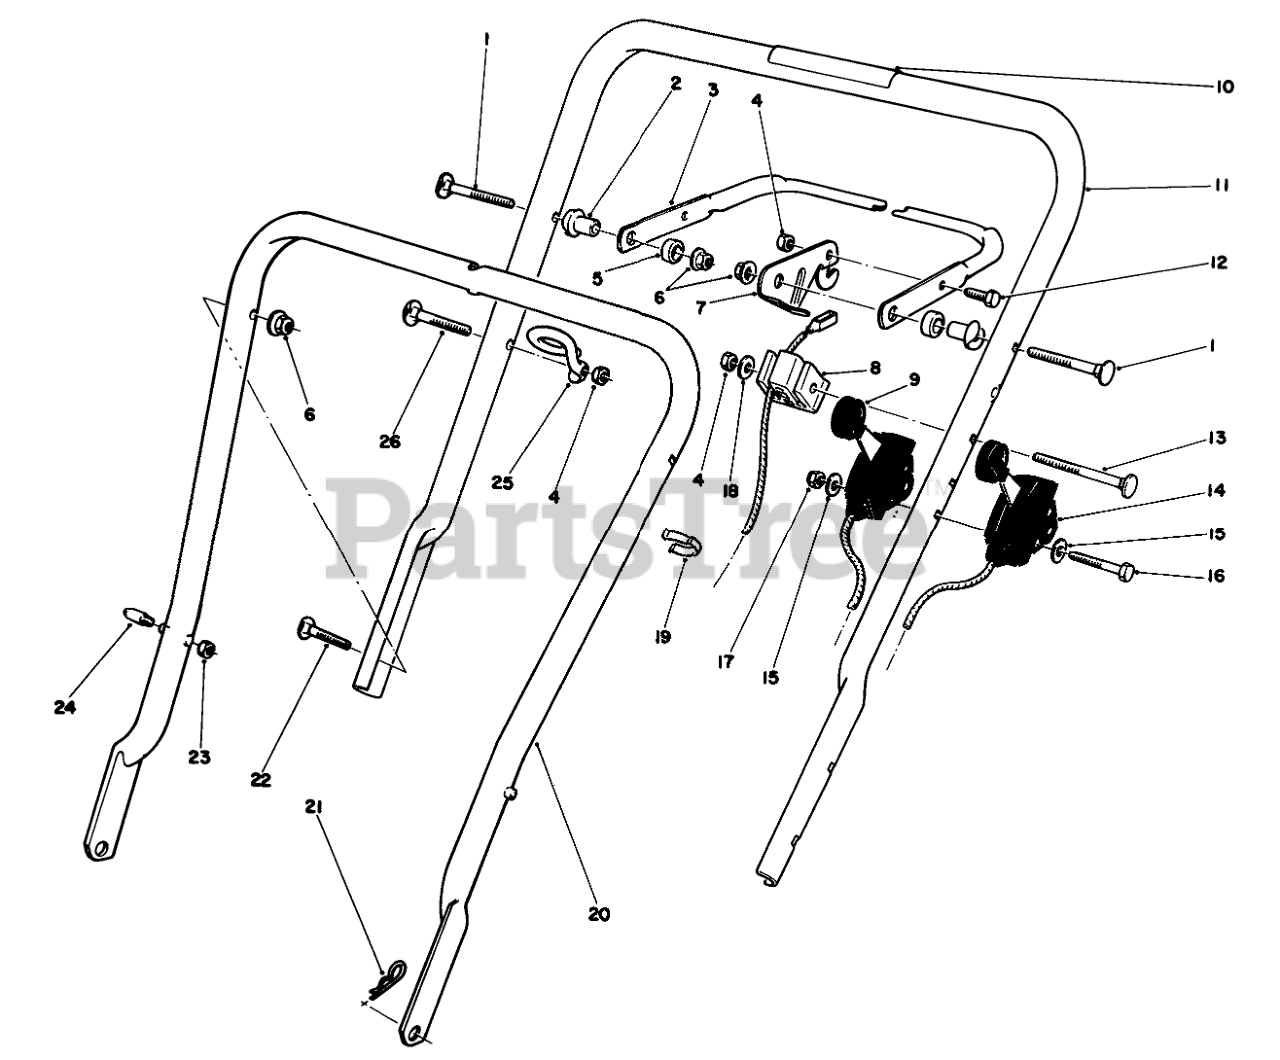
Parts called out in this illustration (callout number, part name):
1	5/16-18 X 2 HNDLE SCREW
2	SPACER-SUPPORT
3	Bar-Control
4	NUT-LOCK, NI
5	SPACER-NYLON
6	NUT-LOCK, NI
7	Lever-Control
8	SUPPORT-CABLE
9	THROTTLE CONT-SERVICE
10	WARNING DECAL
11	Handle-Upper (Incl. Ref. #10)
12	SCREW-HH
13	HANDLE SCREW
14	SERVICE TRACT. CONTROL
15	WASHER-FLAT
16	Capscrew
17	NUT-LOCK, NI
18	WASHER-FLAT
19	BOWDEN CLIP
20	LOWER HANDLE ASM
21	PIN-COTTER, HAIR
22	SCREW
23	NUT-LOCK, NI
24	HANDLE PIN
25	Guide
26	HANDLE SCREW
